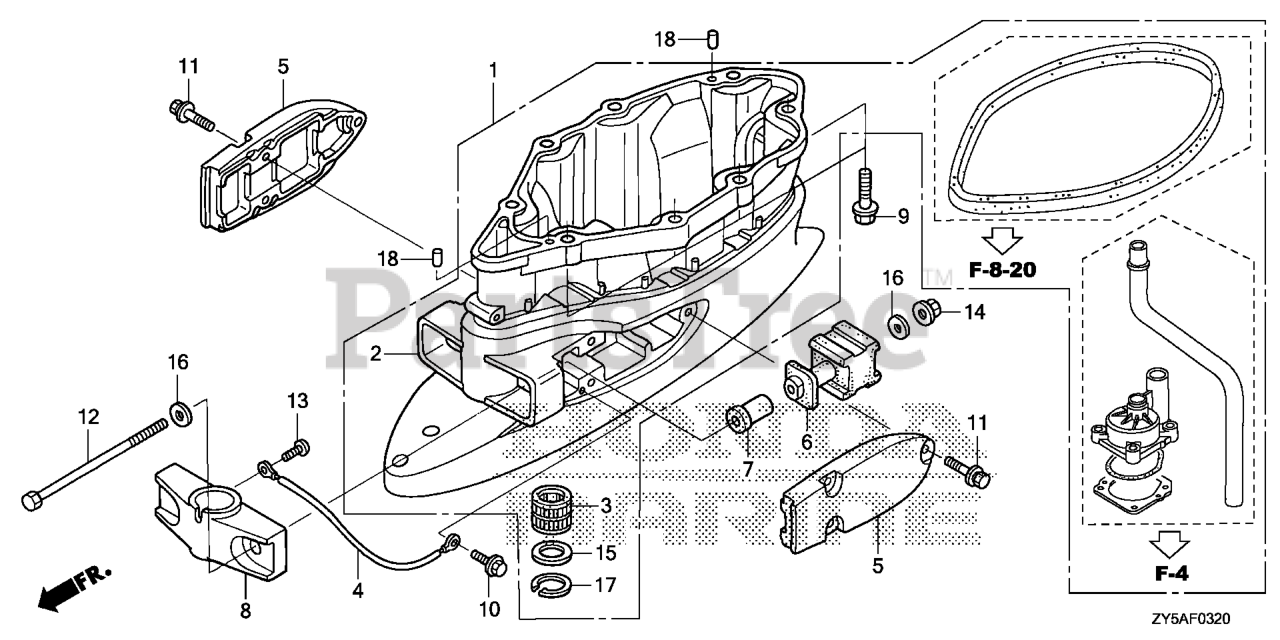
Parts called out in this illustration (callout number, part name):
1	CASE KIT, EXTENSION *NHB14M* (AQUA MARINE SILVER METALLIC) (NOT AVAILABLE)
2	CASE, EXTENSION *NHB14M* (AQUA MARINE SILVER METALLIC)
3	BUSH, VERTICAL SHAFT
4	WIRE, LEAD (1.5X137MM)
5	HOUSING, MOUNTING (LOWER) *NHB14M* (AQUA MARINE SILVER METALLIC)
5	HSG,LWR MT*NH565*
6	RUBBER, MOUNT (LOWER)
7	COLLAR, MOUNTING (LOWER)
8	HOUSING, CENTER MOUNTING (LOWER) *NHB14M* (AQUA MARINE SILVER METALLIC)
8	HSG,LWR MT*NH565*
9	BOLT, FLANGE (10X40)
10	BOLT, FLANGE (6X12)
11	BOLT-WASHER (8X30)
12	BOLT, HEX. (12X225)
13	SCREW, PAN (6X8)
14	NUT, FLANGE (12MM)
15	WASHER (26MM)
16	WASHER, PLAIN (12MM)
17	CIRCLIP (INNER) (40MM)
18	PIN, DOWEL (6X10)
